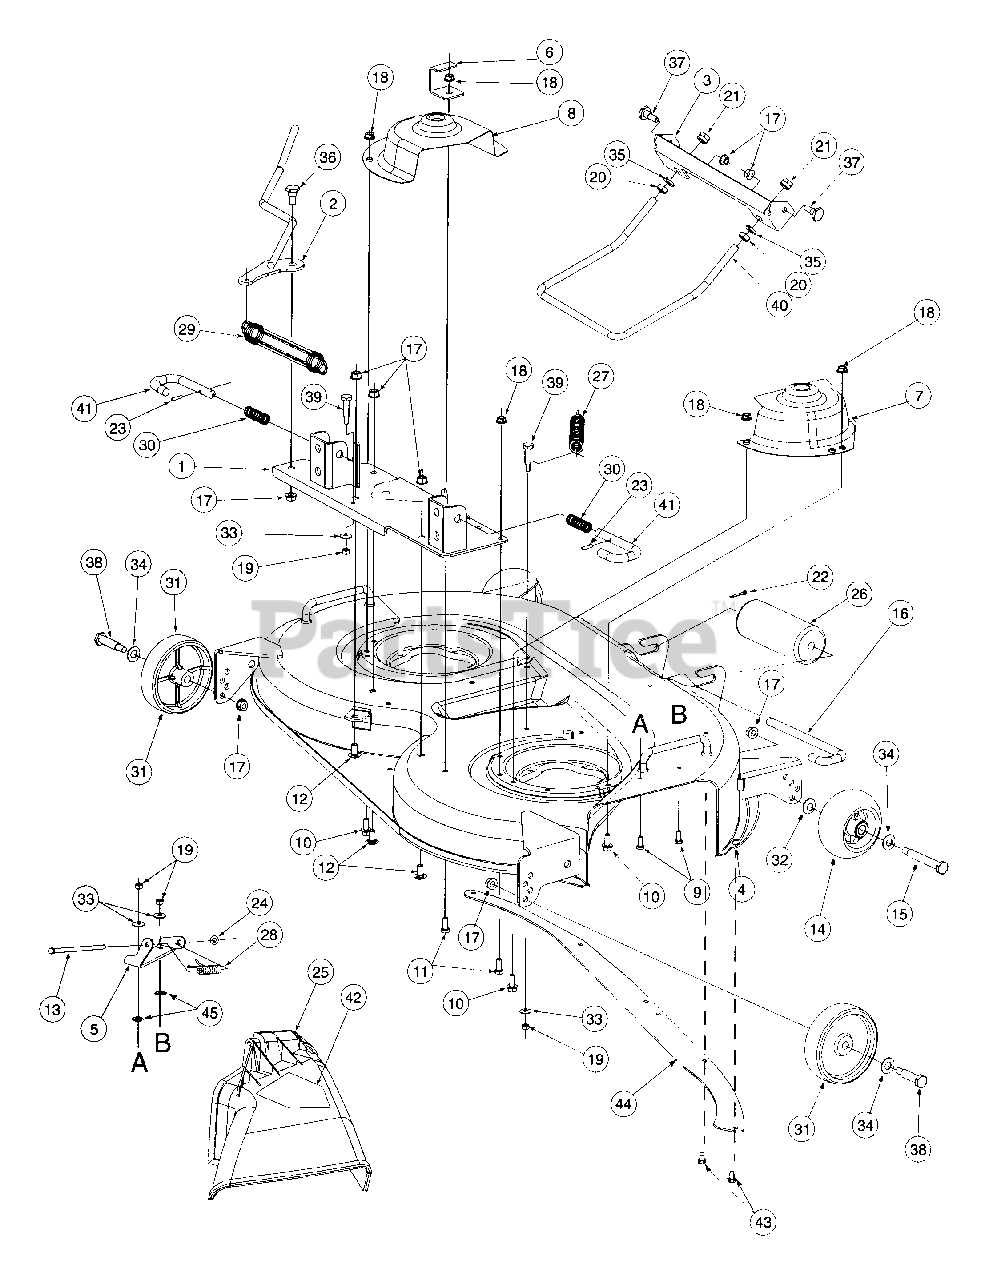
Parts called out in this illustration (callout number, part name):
1	Plate Assembly, Mounting
3	Bracket, Front Lift
4	Deck Assembly
5	Bracket, Hinge Mounting
6	Bracket, Handle Stop
7	Shield, RH Pulley
9	Screw, Hex Cap, 1/4-20 x .62 GR5
10	Screw, Hx Wsh Hd Tapp, 5/16-18 x .75
11	Screw, Hex Cap, 5/16-18 x .75 GR5
12	Bolt, Carriage, 3/8-16 x .75
13	Pin, Hinge, .25 Dia x 6.75 Lg
14	Wheel, Deck w/Fitting
15	Bolt, Shoulder, 1/2 x 2.5
16	Pin, Roller, 1/2 Dia x 7.31 Lg
17	Nut, Hex Flange Lock, 3/8-16
18	Nut, Hex Flange Lock, 5/16-18 GR5
19	Nut, Hex, 1/4-20
20	Nut, Hex Jam, 1/2-13 GR5
21	Nut, Hex Insert Lock, 1/2-13
22	Pin, Cotter, 3/32 x 1.25
23	Pin, Spiral Spring, 3/16 x .75
24	Cap, Speed Nut
25	Deflector Assy,
27	Spring, Extension, .88 OD x 6.12
28	Spring, Torsion
29	Spring, Extension, 1.25 OD x 8.15
30	Spring, Compression
31	Wheel, Deck, 5 in. Dia
32	Washer, Bell, .401 x .870 x .063
33	Washer, Bell, .265 x .75 x .062
34	Washer, Flat, .510 x 1.0 x .060
35	Washer, Lock, 1/2
36	Bolt, Shoulder, .498 Dia x .340 Lg
37	Bolt, Shoulder, .50 Dia x .434 Lg
38	Bolt, Shoulder, .498 Dia x 1.64 Lg
39	Bolt, Shoulder, .375 Dia x 1.16 Lg
40	Rod, Front Lift
41	Pin, Mower Support
42	Graphic, Danger
43	Screw, Self Tapping, 1/4-20 x .5
45	Nut, Push, 1/4
